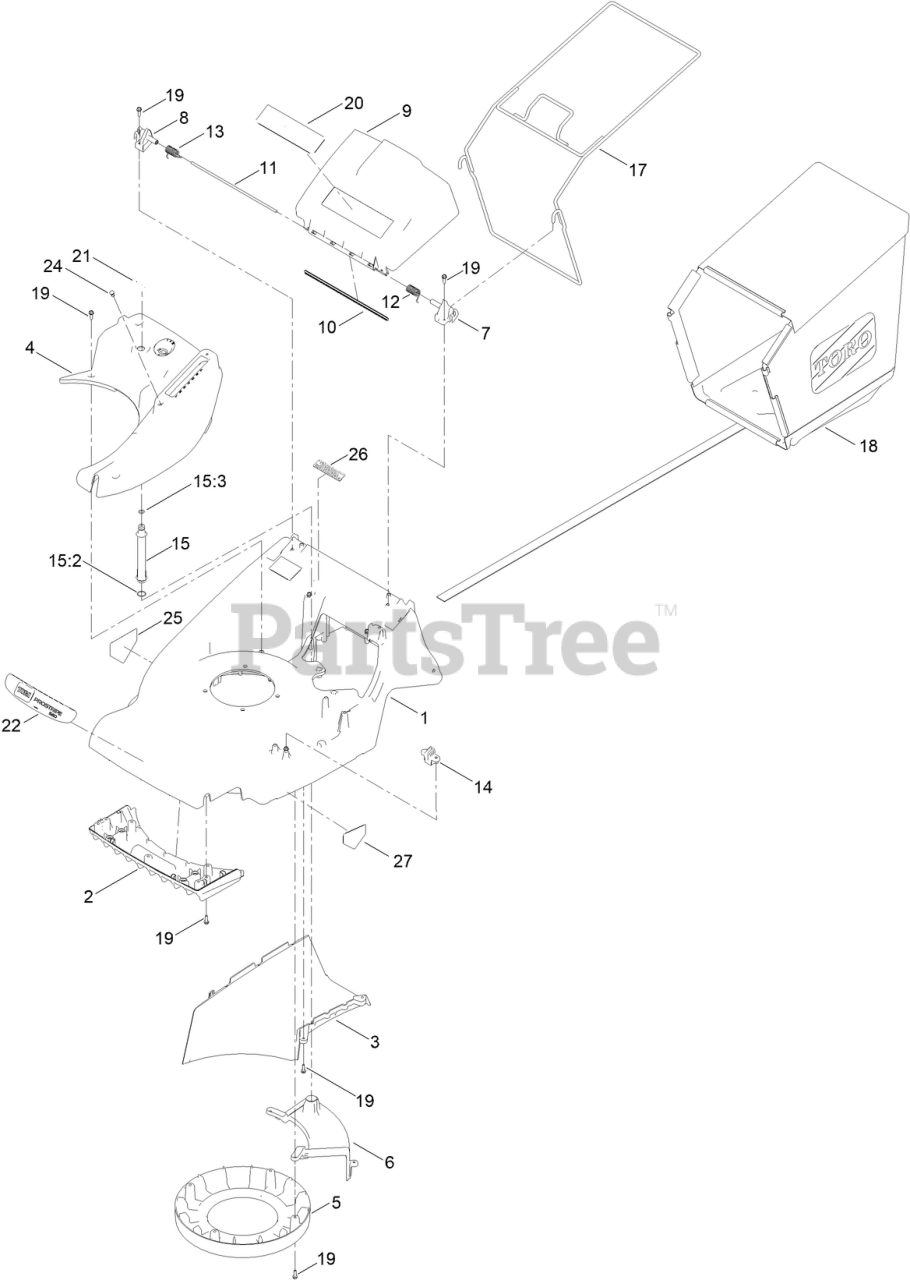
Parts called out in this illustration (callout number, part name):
1	HARRIER DECK ASSEMBLY
2	FINS-FRONT
3	PLATE-THROW
4	TRIM-TOP
5	COVER-BELT
6	COVER-BELT
7	MOUNT-DEFLECTOR, LEFT
8	DEFLECTOR MOUNT RIGHT
9	DEFLECTOR-REAR
10	DEFLECTOR-SEAL, REAR
11	ROD-DEFLECTOR
12	SPRING-DEFLECTOR, LEFT
13	SPRING-DEFLECTOR, RIGHT
14	ROD-SUPPORT
15	WASHPORT ASM, YELLOW
15:2	O-RING SEAL
15:3	O-RING SEAL
17	GRASSBAG-FRAME
18	FABRIC GRASSBAG, TORO
19	SCREW-TAPTITE
20	DECAL-SAFETY
21	DECAL-QUICK WASH
22	DECAL-PROSTRIPE 560
24	RIVET-PUSH, PLASTIC
25	DECAL-DANGER
26	DECAL-ARRESTOR, SPARK
27	DECAL-DANGER
